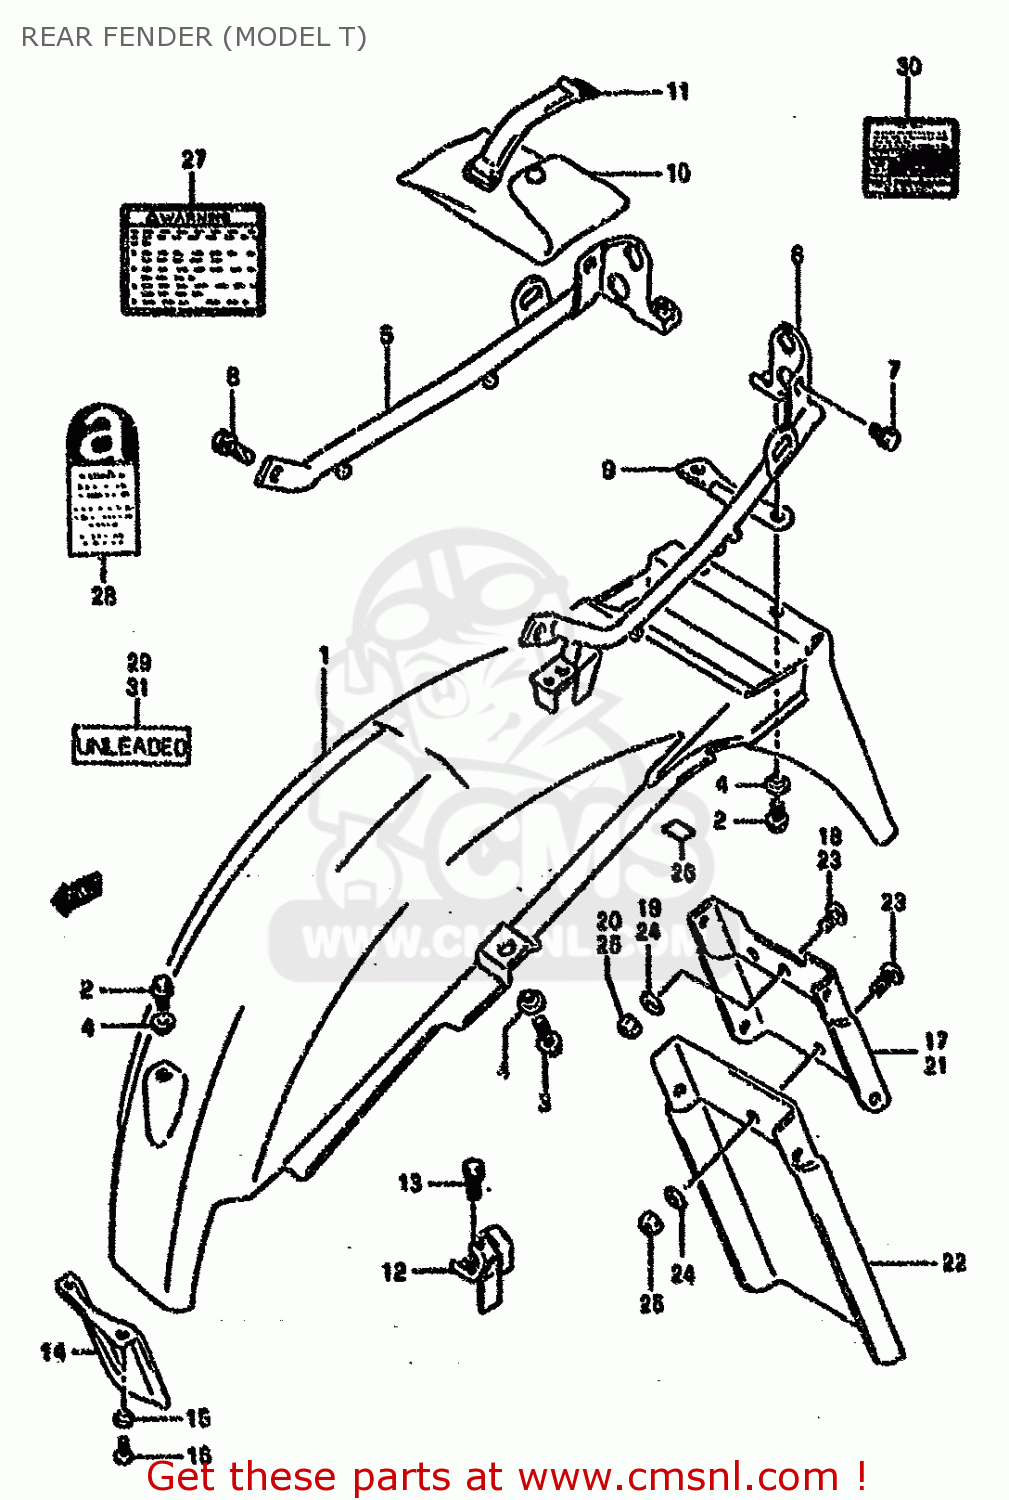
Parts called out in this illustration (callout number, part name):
1	BODY,RR FENDER
2	BOLT
3	BOLT
4	WASHER
5	BRACE,RR FENDER,R
6	BRACE,RR FENDER,L
7	BOLT
8	BOLT
9	PLATE,TOOL HOLDER
10	TOOL ASSY
11	BAND
12	HOLDER,HELMET
13	BOLT
14	GUARD,RR UNIT MUD
15	WASHER
16	SCREW
17	EXTENSION,RR FENDER
18	SCREW
19	WASHER(6.5X16X1.2)
20	NUT
21	EXTENSION,RR FENDER
22	MUDGUARD,RR FENDER
23	SCREW
24	WASHER(6.5X16X1.2)
25	NUT
26	TAPE,RR FENDER
27	LABEL
28	LABEL,ASBESTOS WARNING
29	LABEL,CAUTION
30	LABEL,TIRE AIR PRESSURE
31	MANUAL,OWNER'S
32	CLAMP
33	O.M. GS500E T
